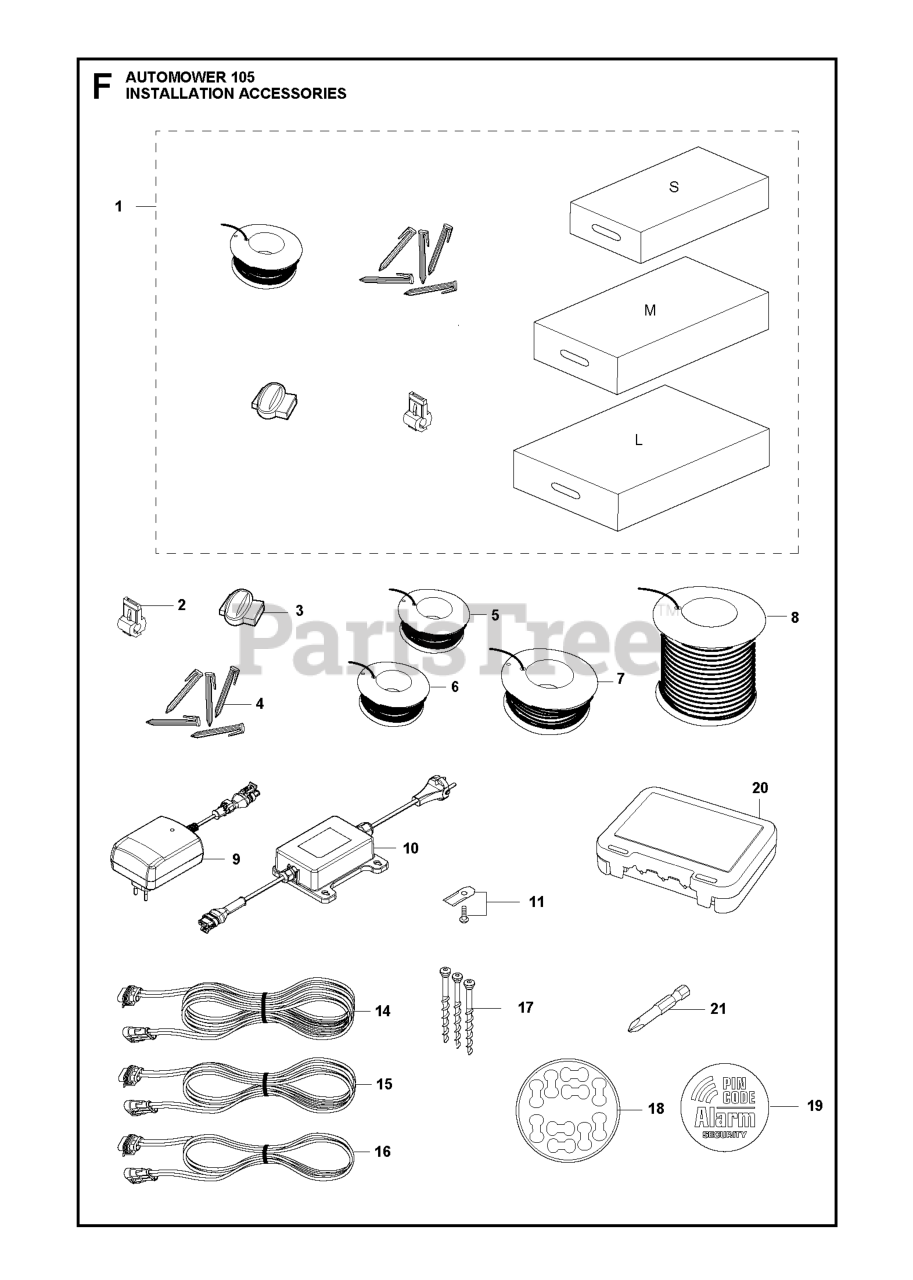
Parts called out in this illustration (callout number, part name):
1	SMALL AUTOMOWER INSTALL KIT
1	MED AUTOMOWER INSTALL KIT
1	LARGE AUTOMOWER INSTALL KIT
2	BRAKER
2	CONNECTOR 5 PCS, BLISTER
2	CONNECTOR 100 PCS
3	SPLICE KIT
3	COUPLER SPLICER, 5 PCS,
3	COUPLER SPLICER, 100 PCS
4	STAPLE 100 PCS, BLISTER
5	WIRE 50M STANDARD Ø2.7MM,BLIST
8	WIRE (800M)
9	POWER UNIT POWER SUPPLY 1,3A
11	HUS BLADE SET 9 PCS
11	HUS BLADE SET 45 PCS
11	HUS BLADE SET 300 PCS
14	CABLE ASSY LOW VOLTAGE CABLE
15	CABLE ASSY LOW VOLTAGE CABLE
16	CABLE ASSY LOW VOLTAGE CABLE
17	SCREW 3 PCS, BLISTER PACK
18	STICKER CABLE MARKERS KIT 10PC
19	LABEL SECURITY
20	CONNECTOR PROTECTION BOX
21	WRENCH BITS CHANGING ROBOTIC B
